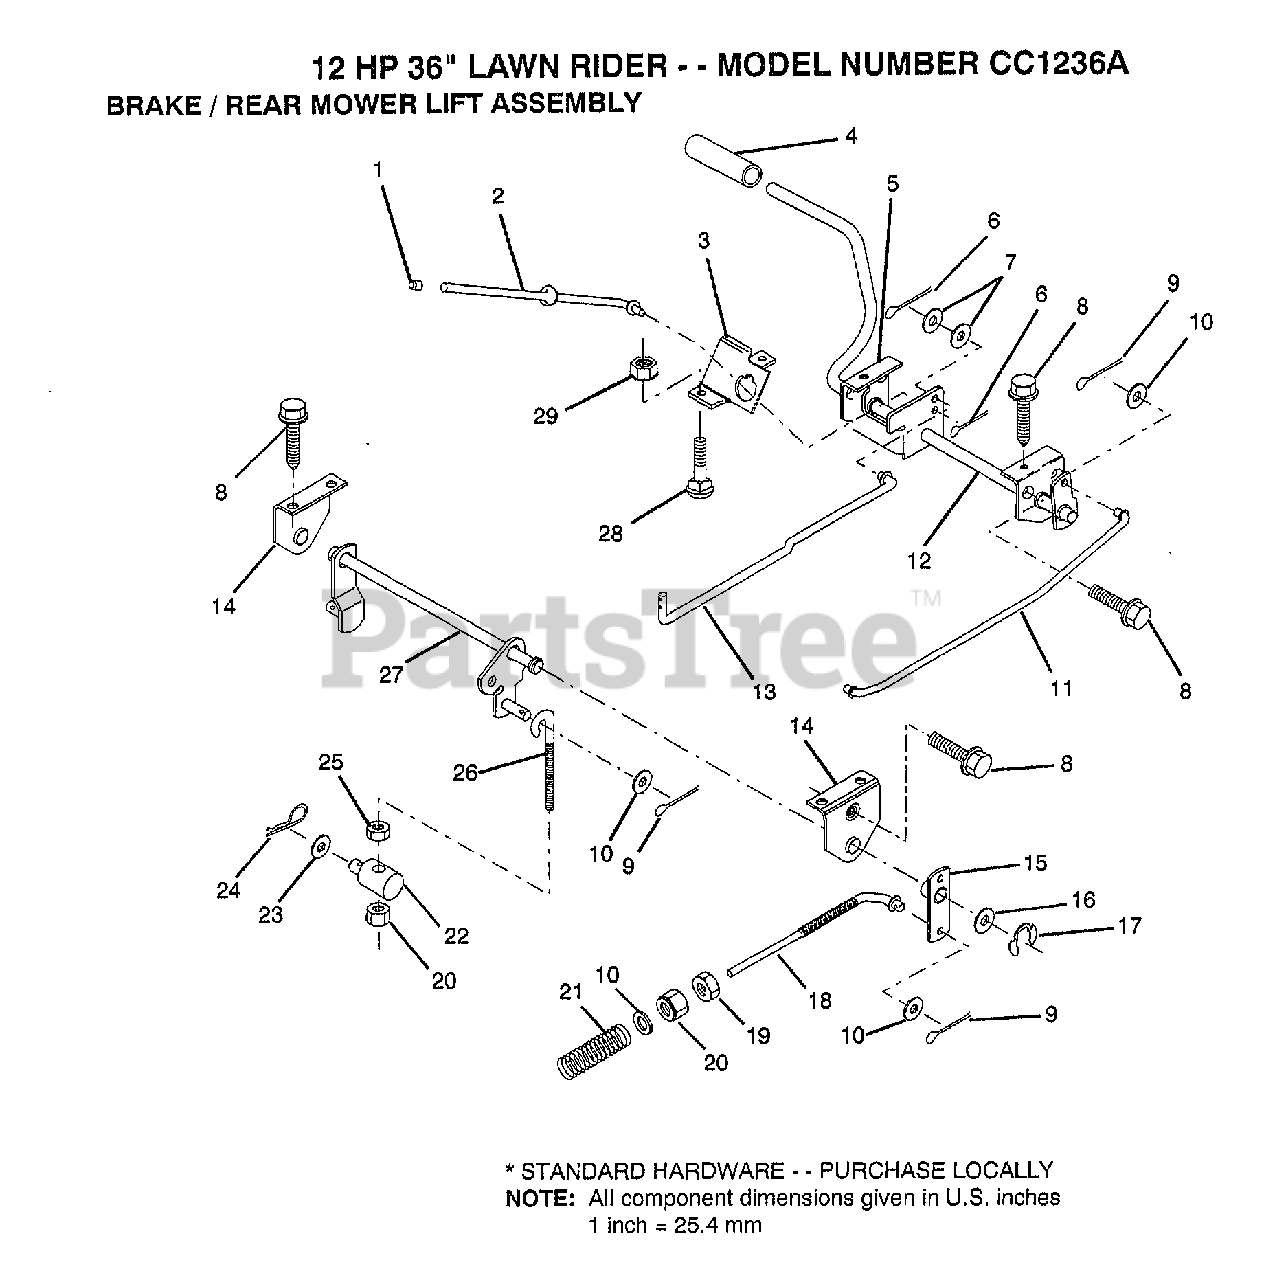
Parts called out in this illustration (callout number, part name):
1	PLUNGER CAP T
2	"ROD,PARK BRAKE"
3	"BRKT,PARK BRAKE"
4	PEDAL COVER T
5	"BRKT,CLU PEDAL LH"
7	WASHER
8	SCREW LT
9	COTTER PIN
10	WASHER
11	"ROD,FRT BRAKE"
13	"ROD,CLUTCH"
14	"BRKT,LIFT SHAFT"
15	BRAKE PIVOT ARM
16	WASHER T
17	KLIP RING
19	NUT
21	SPRING ROD LT
23	WASHER
24	SPRING.RETAINER
25	LOCKNUT
26	"LINK, MOWER REAR"
